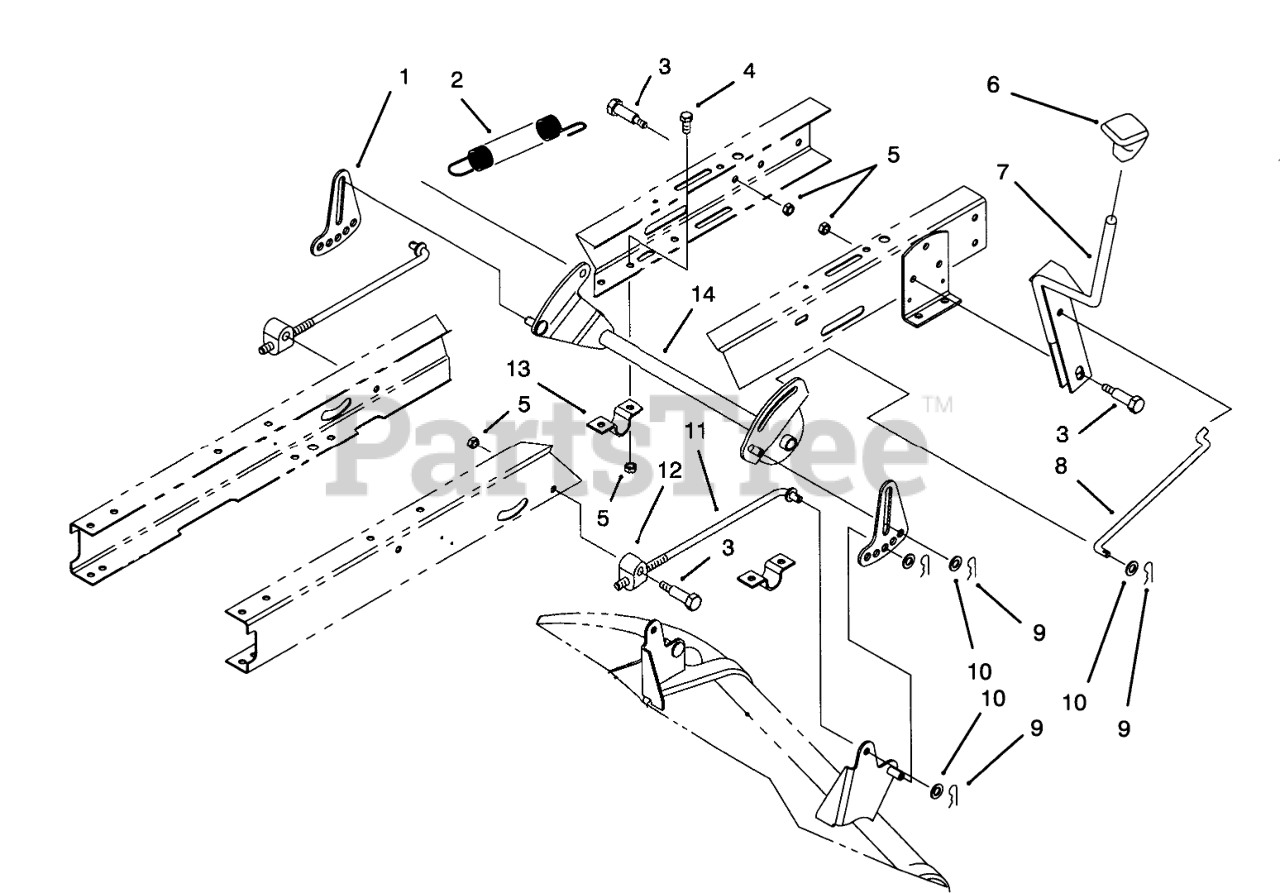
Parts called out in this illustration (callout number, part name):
1	Link-Adjusting H.O.C
2	SPRING-EXTENSION
3	SCREW-SHOULDER, HH
4	SCREW-HH
5	NUT-LOCK, NI
6	SHIFT KNOB
7	Lever-H.O.C.
8	LINK-HOC
9	PIN-COTTER
10	WASHER-FLAT
11	ROD-HANGER, REAR
12	TRUNNION-HOC
13	CLAMP-PIVOT, HOC
14	Pivot-H.O.C.
